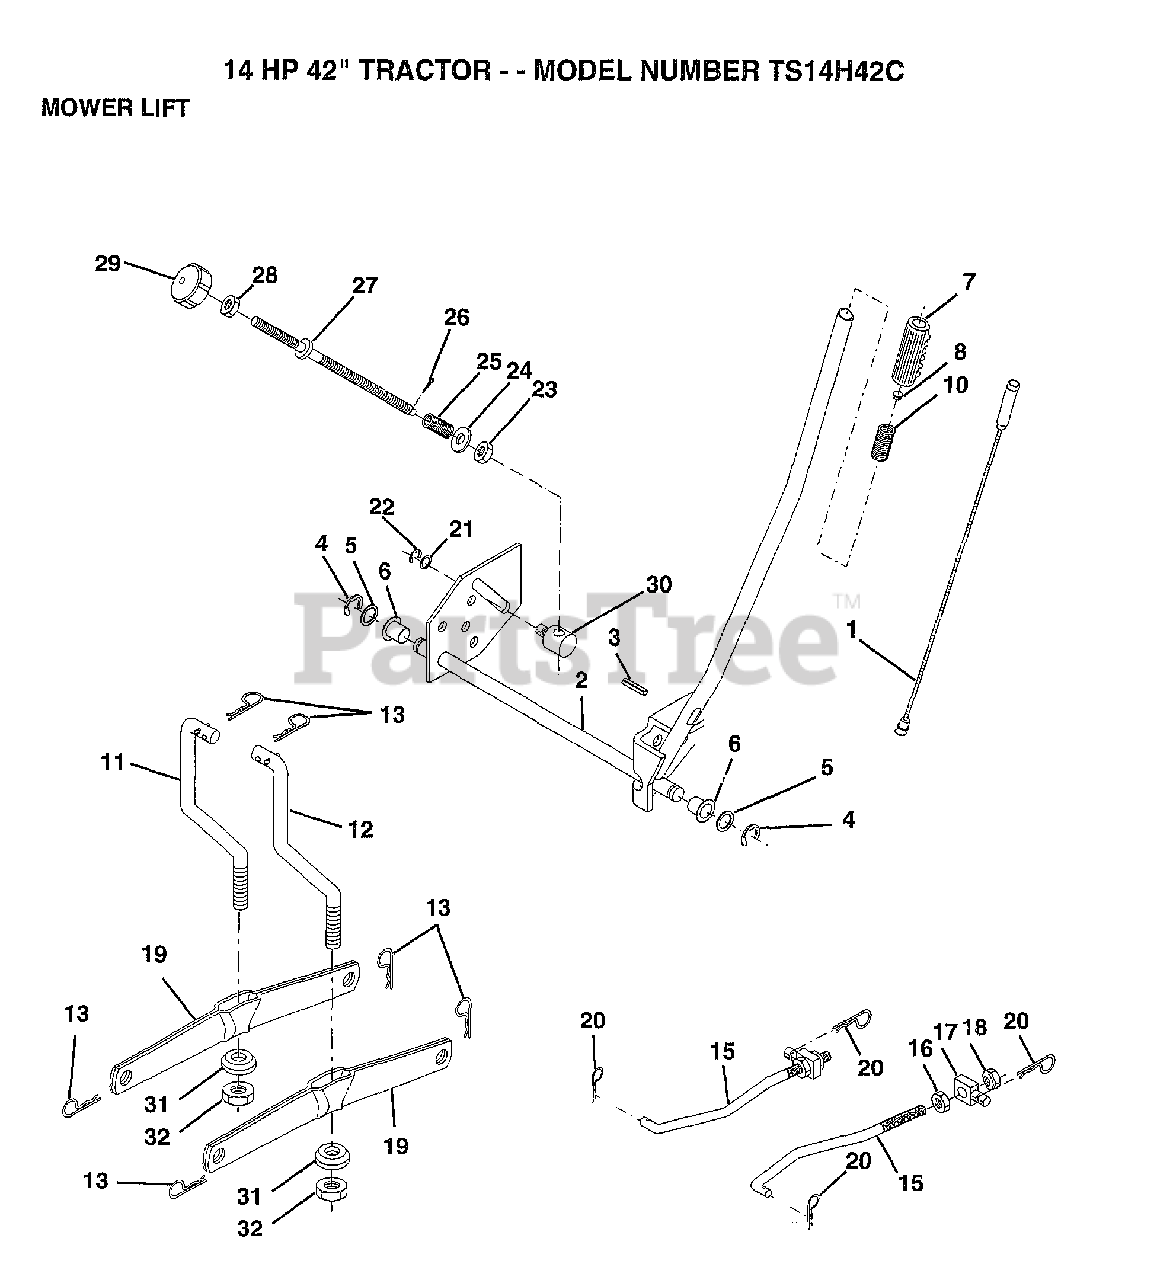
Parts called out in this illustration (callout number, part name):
1	WIRE.ASM.INNER
2	SHAFT.ASM.LIFT.RH
3	PIN GROOVE
5	WASHER
6	NYLON BEARING
7	GRIP HANDLE
15	LINK.FRONT
16	NUT
17	TRUNION
18	NUT.LK.W/WSH.1/2.
19	ARM SUSP REAR
20	RETAINER.SPRING
21	WASHER
22	KLIP RING
23	NUT T
24	WASHER
25	SPRING T
27	ROD LIFT LT
28	NUT
29	KNOB INF 3/8-16
30	TRUNION LT
31	BEARING PVT LH
32	NUT.LOCK.3/8-24
